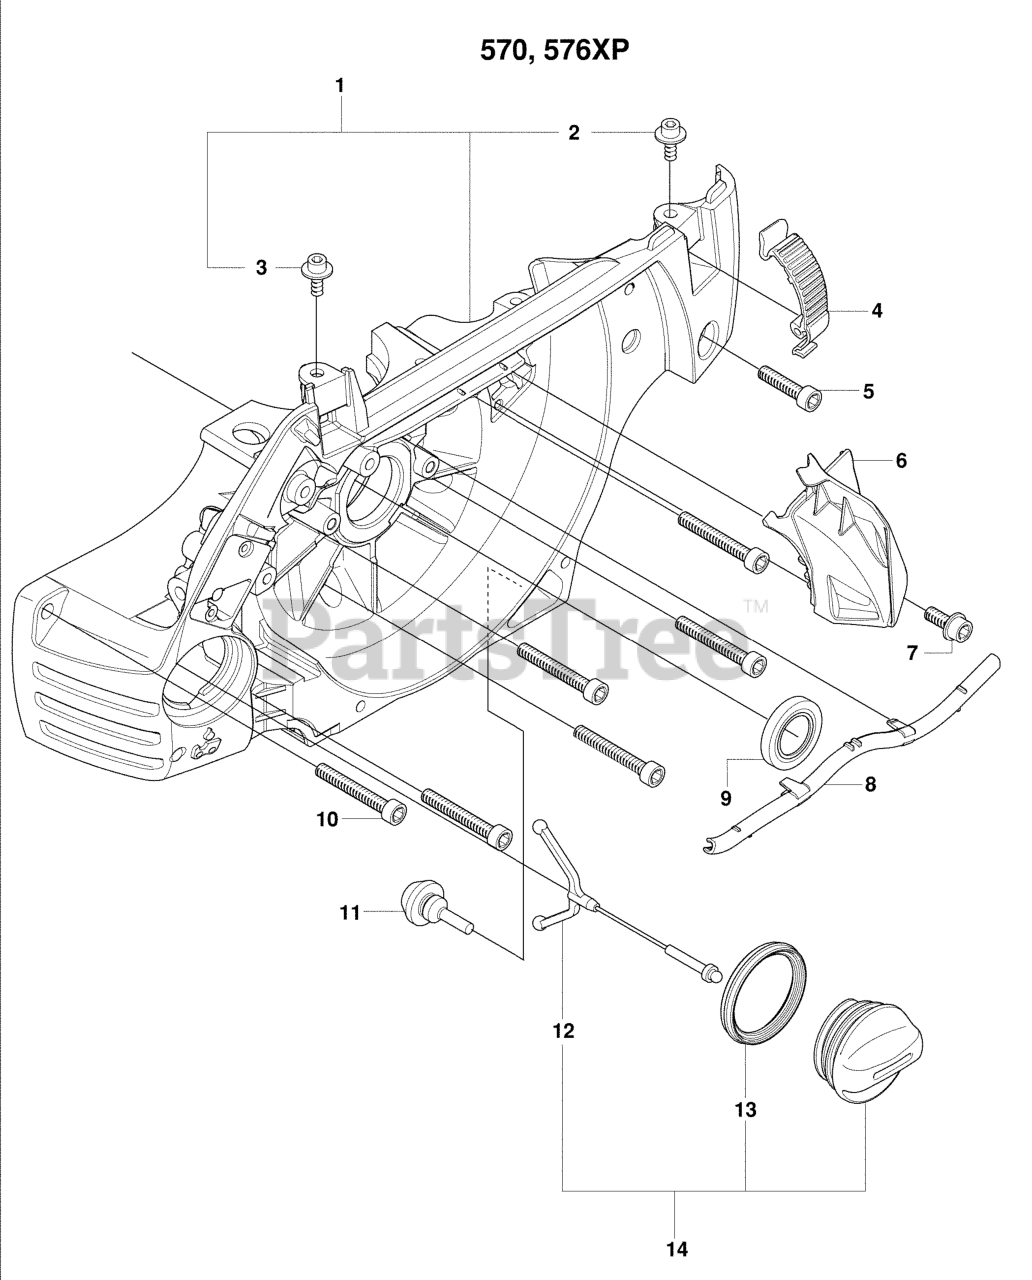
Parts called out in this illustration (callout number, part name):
1	RP CRANKCASE ASSEMBLY
1	CRANKCASE ASSY
2	SCREW IHSCM
3	SCREW IHSCM
4	BUCKLE ORANGE
4	CLIP GRAY
9	SEAL RING
9	RADIAL SEAL
13	SEALING
14	TANK CAP
